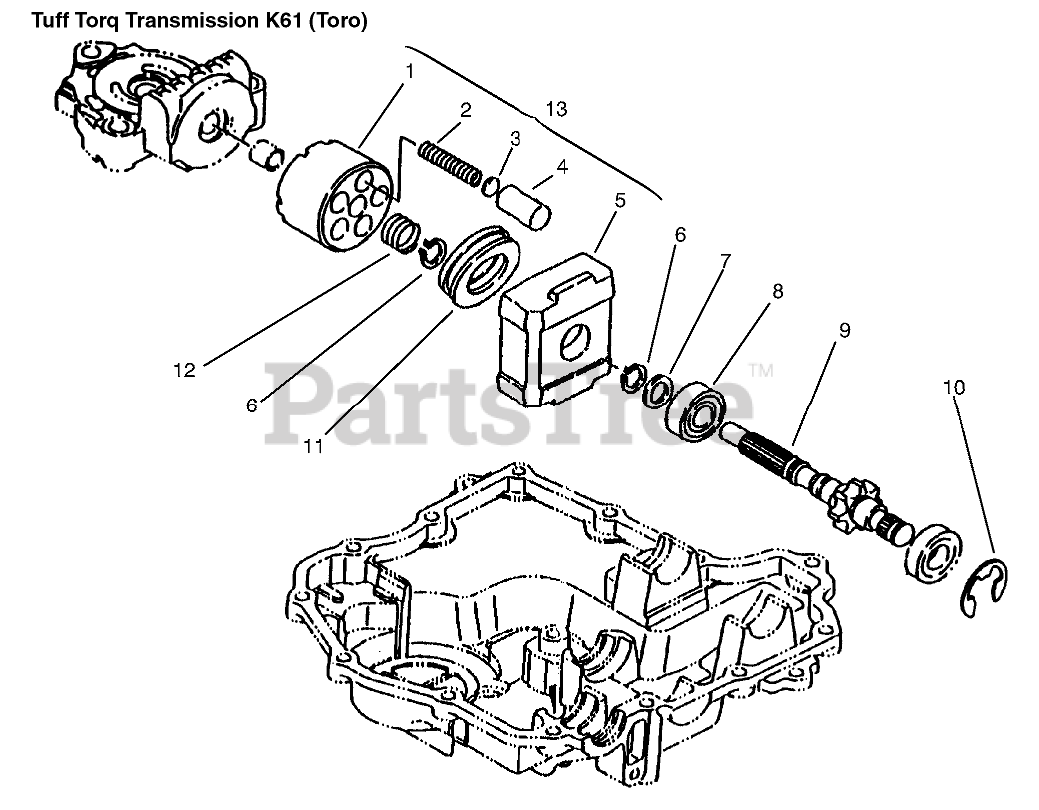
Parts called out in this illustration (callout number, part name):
1	Block-Cylinder
3	Washer
5	HOUSING
6	RING-SNAP
7	WASHER
8	BEARING-BALL
9	SHAFT - MOTOR
10	E-RING
11	BEARING-THRUST
13	ASM - CYCLINDER INC 6-9
